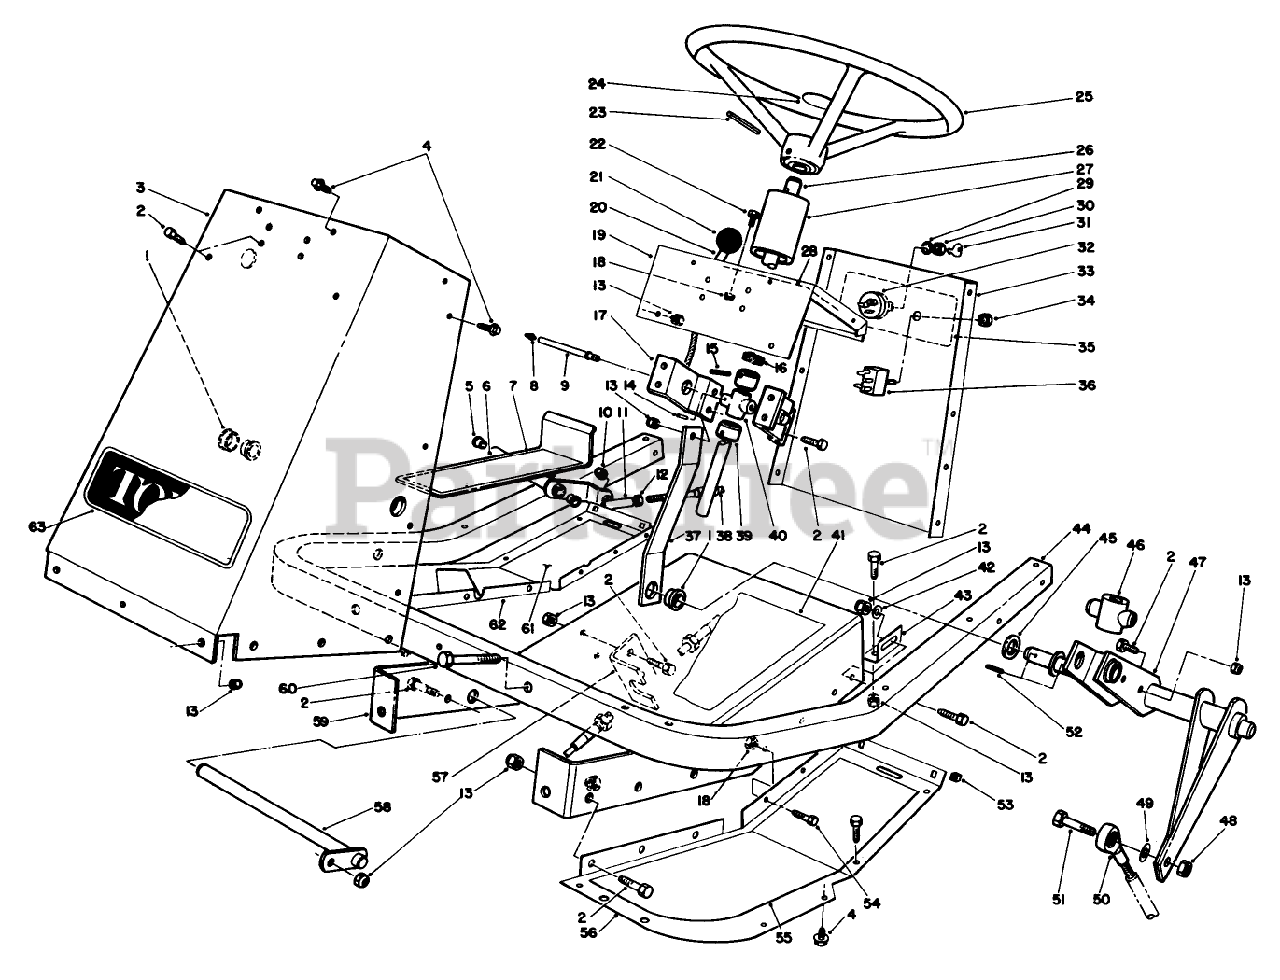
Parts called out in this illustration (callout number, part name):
1	BEARING-FLANGE
2	SCREW-HH
3	Tower-Front
4	SCREW-HHFTF
5	BUSHING-FLANGE
6	Traction Pedal (Incl. Ref. #5)
8	FITTING-GREASE
9	TUBE ZERK
10	NUT-LOCK
11	JOINT-BALL
12	NUT-JAM
13	NUT-LOCK, NI
14	3/32 X 9/16 ROLL PIN
15	PIN-SPRING
16	COVER-DUST
17	BRG SUPT BRKT
18	NUT-LOCK, NI
19	Tower-Top
20	CONTROL-CHOKE,THROTTLE
22	SCREW-HH
23	PIN-ROLL
24	STEERING WHEEL CAP
25	STEERING WHEEL
26	Shaft-Steering
27	STRG. SHAFT COVER
28	THROTTLE DECAL
29	Washer-Lock
30	Nut-Hex
31	Key
32	Switch-Ignition (Incl. Ref. #29-31)
33	REAR TOWER PANEL R
34	NUT
35	SWITCH DECAL
36	Switch
37	Link-Steering
38	TRACT CONT.CABLE
39	STRG SHAFT COLLAR
40	BRG STEERING SHAFT
41	TUNNEL DECAL
42	WASHER-PLAIN
43	TUNNEL BRKT
44	Frame-Footrest
45	WASHER-THRUST
46	STEER.SHAFT FOLLOWER
47	Follower Lever
48	NUT-HEX
49	WASHER-FLAT
50	BALL JOINT LH
51	SCREW-HH
52	PIN-ROLL
53	NUT-RETAINED
54	SCREW-HH
55	FOOT REST PAD LH
56	Footrest-L.H.
57	TRACT CABLE BRKT
58	PEDAL.SHAFT WA
59	Tunnel
60	SCREW-HH
61	FOOT REST PAD RH
62	Footrest-R.H.
63	Decal-Toro
